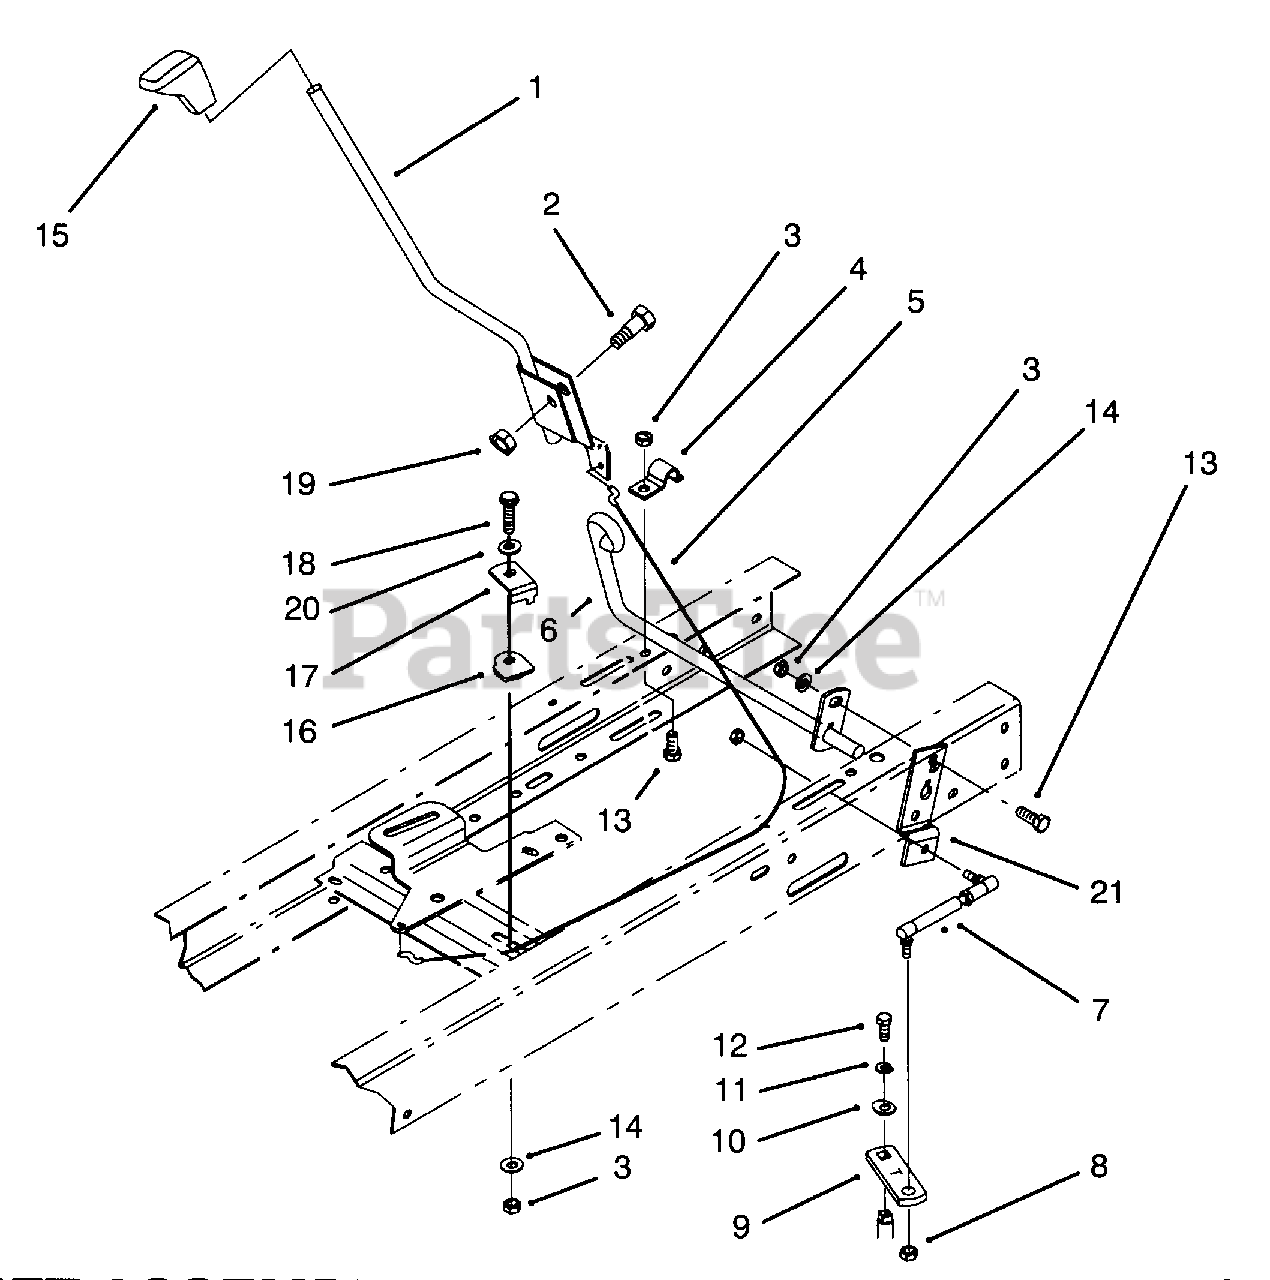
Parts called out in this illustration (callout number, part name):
1	Lever-Shift
2	Bolt-Shoulder
3	Nut-Lock
4	Clamp-Shift Pivot
5	Cable-Shotgo
6	Pivot-Shift
7	Rod-Shift Tie
8	Nut-Lock
9	Lever-Trans. Shift
10	Washer-Hardened
11	Washer-Lock
12	Screw-Hex Hd. Cap
13	Screw-Hex Hd. Cap
14	Washer-Flat
15	Knob-Shift
16	Guide-Cable
17	Keeper-Cable
18	Bolt-Carriage
19	Nut-Lock
20	Washer-Flat
21	Lever-Shift Pivot
